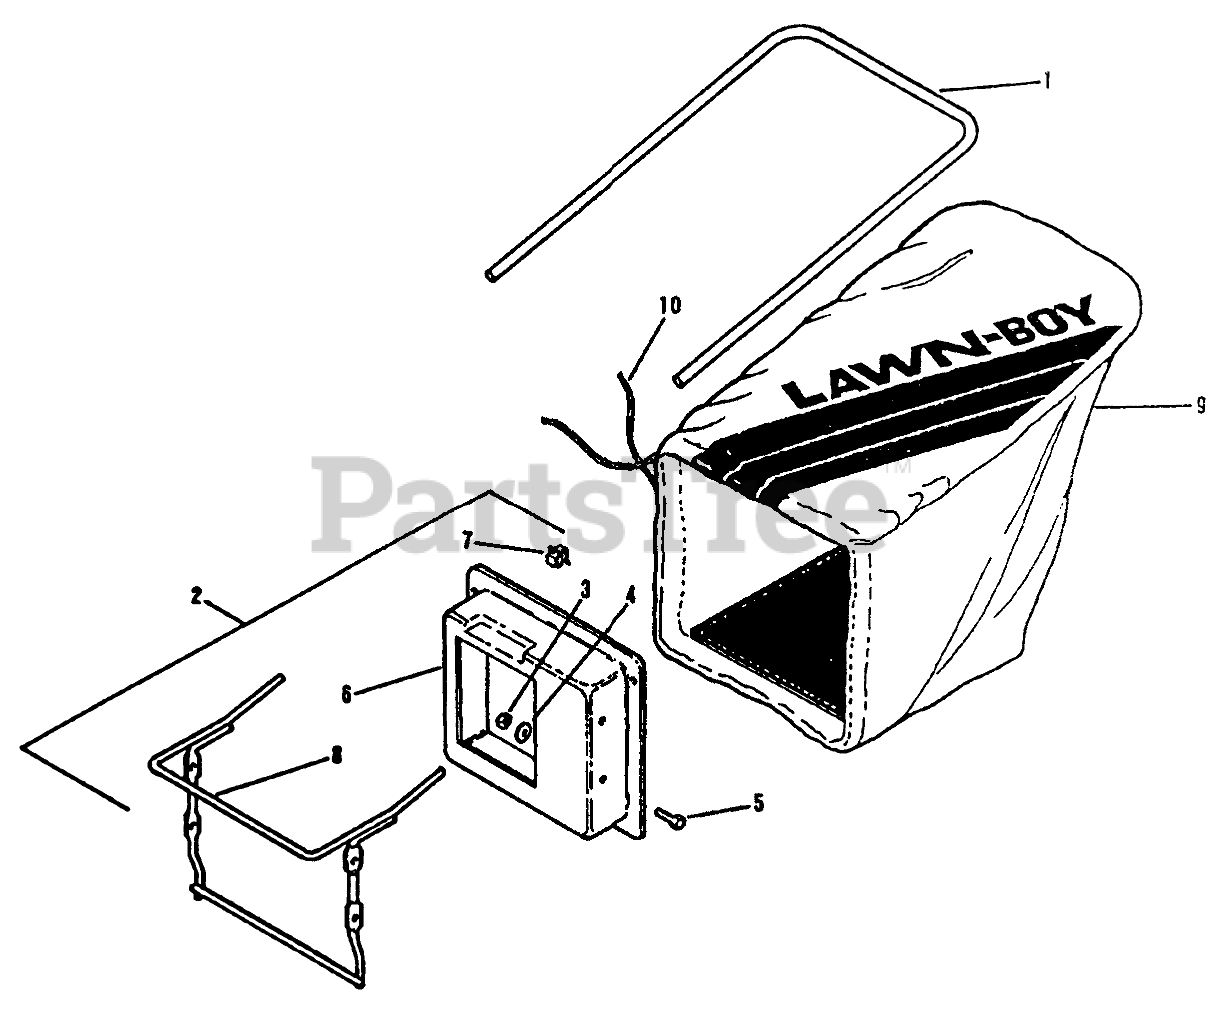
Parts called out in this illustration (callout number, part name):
1	HANGER BAG TROX
2	Bag Adapter Assembly
3	LOCKNUT E
4	WASHER
5	Screw
6	BAG ADAPTOR PL
7	S CLIP ARDEN
8	LATCH BAR AY ARGO
9	Bag-Grass
10	ROPE S
